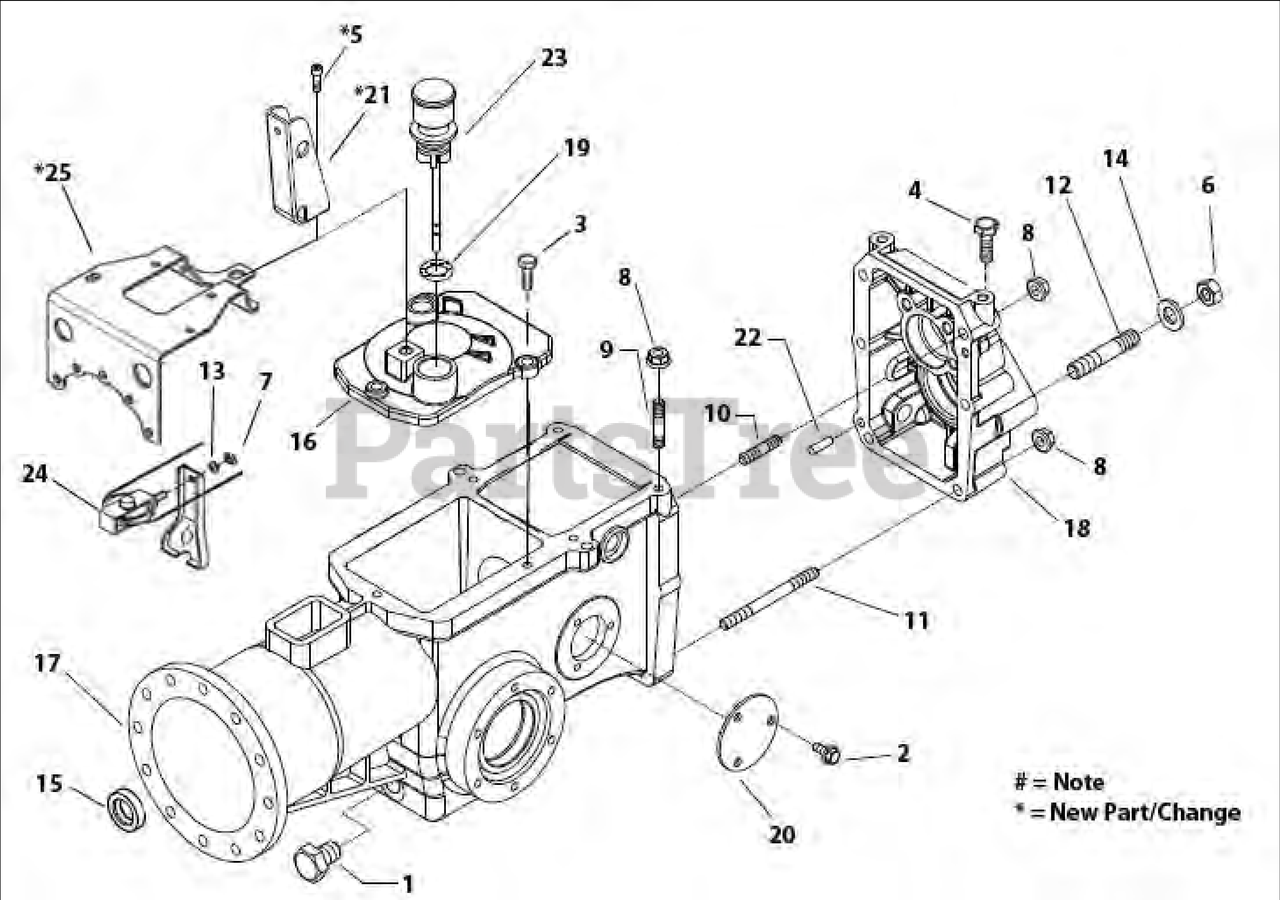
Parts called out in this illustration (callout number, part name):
1	PLUG, 1/4
2	CAP SCREW, M6X12
3	CAP SCREW, M8X30 FLANGED HEAD
4	CAP SCREW, M8X20
5	CAP SCREW, M10X25
6	NUT, M12 (TIGHTEN TO 60 FT LBS)
7	NUT, SELF LOCKING M8
8	NUT, SELF LOCKING DEFORMED M8
9	STUD M8X38X14X20
10	STUD M8X58X16X16
11	STUD M8X68
12	PTO STUD M12X1.25X12X64
13	WASHER M8
14	WASHER TAPERED M13X24X3
15	OIL SEAL 15X28X7
16	GEAR BOX COVER
17	GEAR BOX CASE
18	REAR END COVER
19	O-RING , DIPSTICK
20	SIDE COVER
21	CLUTCH CABLE BRACKET ( Recoil Start Only)
22	PARALLEL PIN
23	DIP STICK VENTED W/CAP
24	PULLEY ASSEMBLY (Electric Start Only)
25	SUPPORT BRACKET
